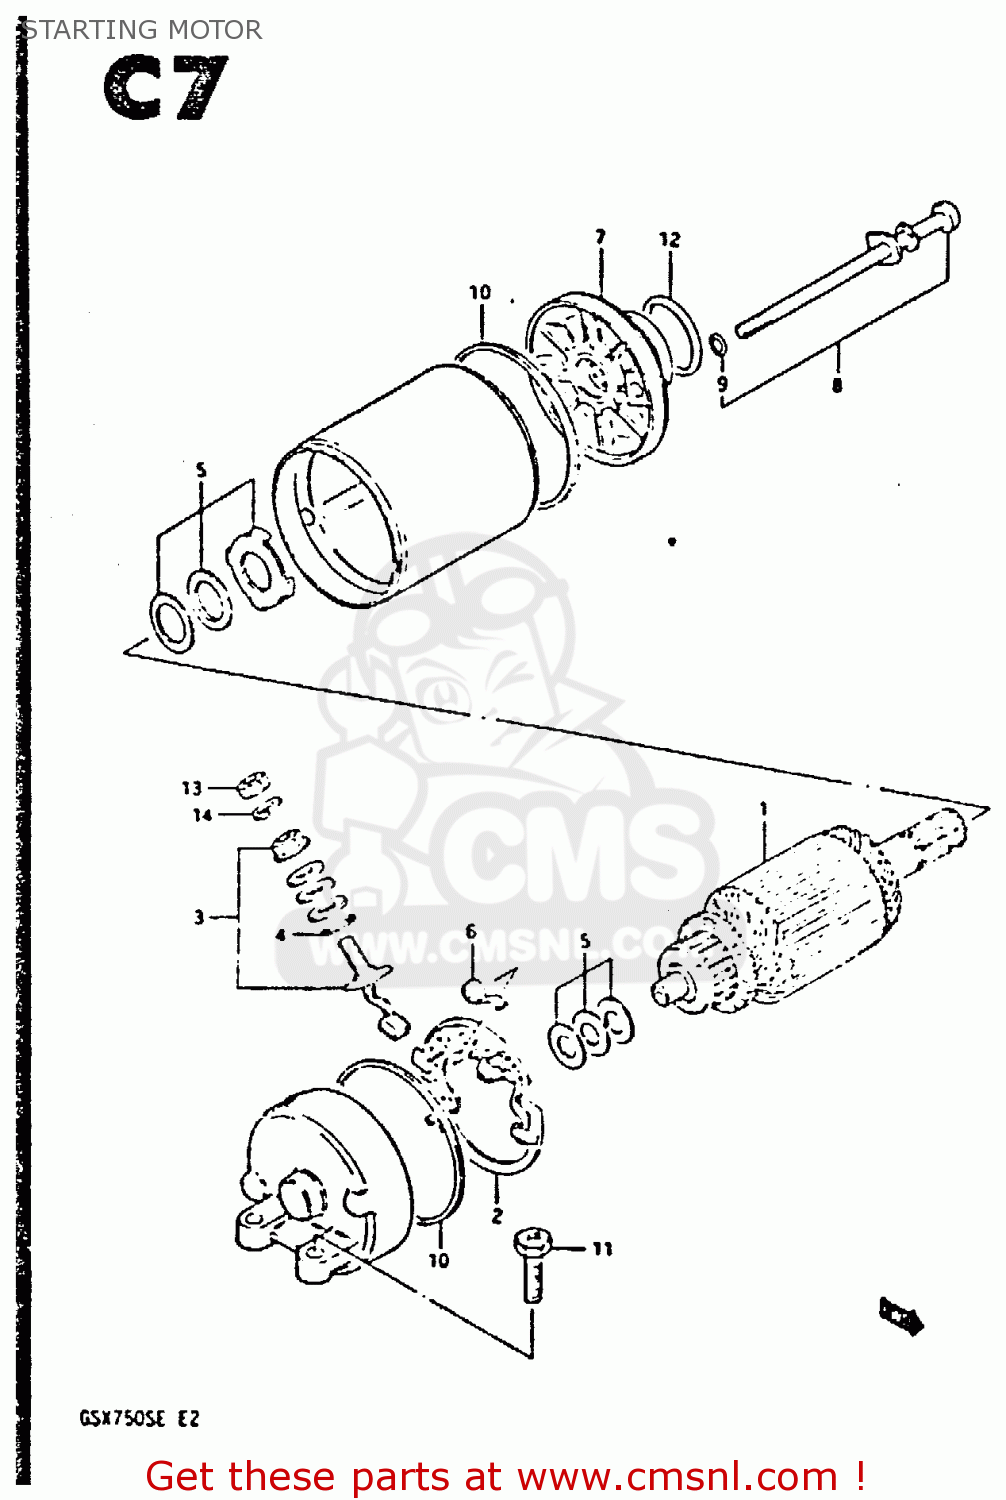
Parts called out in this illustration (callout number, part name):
1	ARMATURE
2	HOLDER SET,BRUSH(-)
3	TERMINAL SET,BRUSH,PLUS
4	O RING
5	SHIM SET,STARTING MOTOR
6	SPRING,BRUSH
7	BRACKET SET,STARTING MOTOR
8	BOLT SET,STARTING MOTOR
9	O RING
10	O RING
11	SCREW (6X25)
12	O RING(D:3,ID:24.5)
13	NUT
14	WASHER,LOCK
